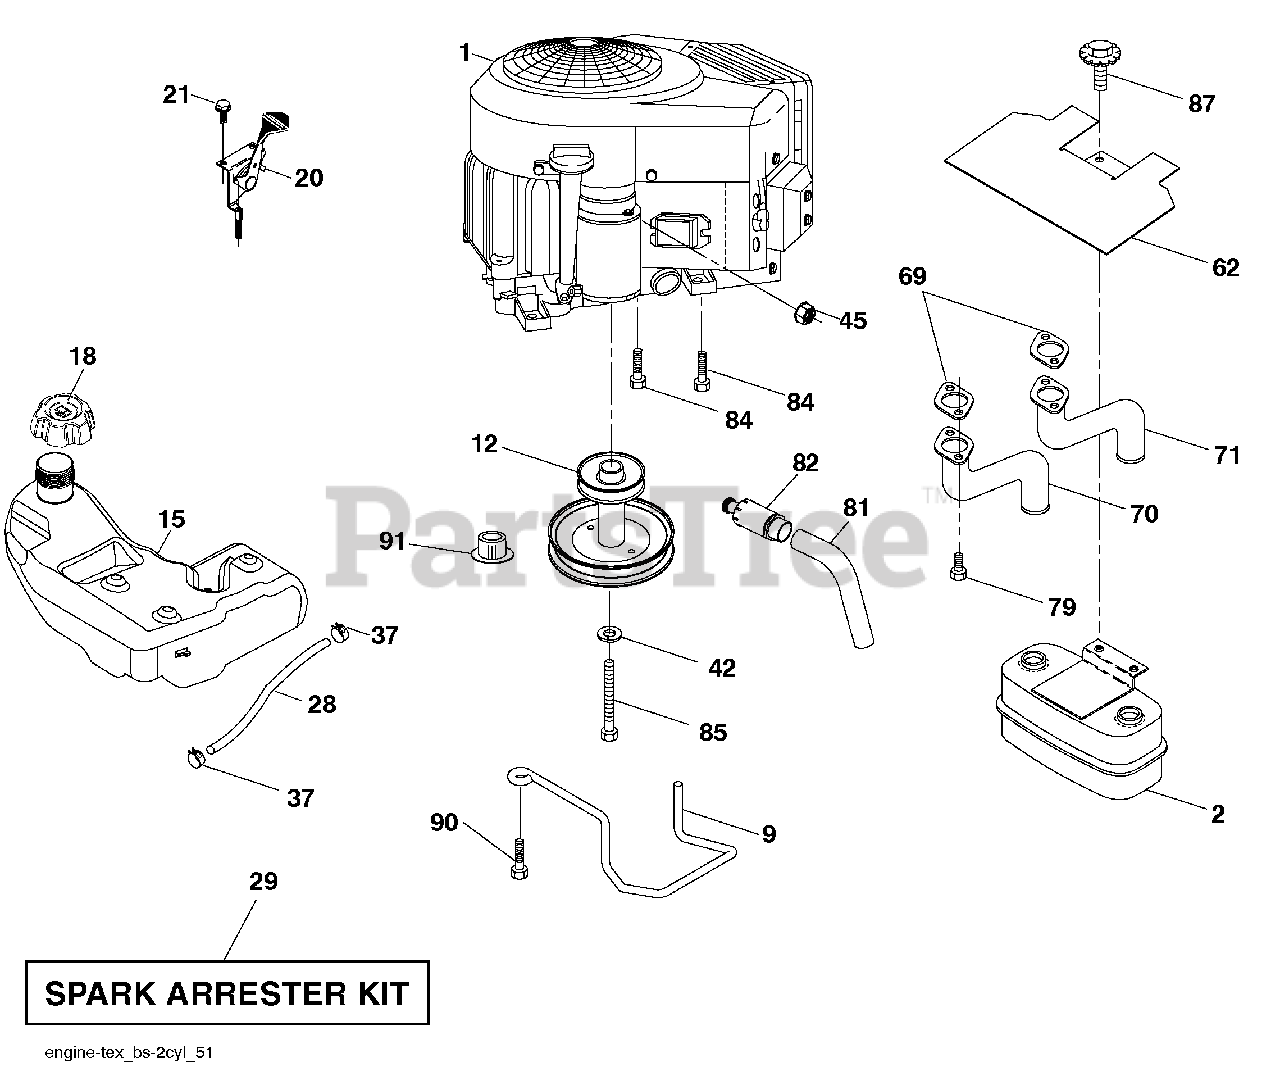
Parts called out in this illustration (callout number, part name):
2	Muffler
9	Keeper Belt Engine
12	Pulley Engine
15	Tank Fuel
18	Cap Fuel
20	Control Throttle/Choke
21	Screw #10 x 0.750 BOS Thread
28	Fuel Line
29	Spark Arrester Kit
37	Clamp Hose
42	Washer Lock 7/16
45	Nut Keps Hex 1/4-20 unc
62	Shield Heat Muffler
69	Gasket
70	Exhaust Tube LH
71	Exhaust Tube RH
79	Screw Socket HD 5/16-18 x 1
81	Tube Drain Oil Easy
82	Valve Drain Oil
84	Screw 3/8-16 x 1-1/4
85	Bolt 7/16-20 x 4 x Gr. 5-1.5
87	Bolt 5/16 - 18 x 3/4
90	Screw 3/8-16 x 1
91	Bushing
